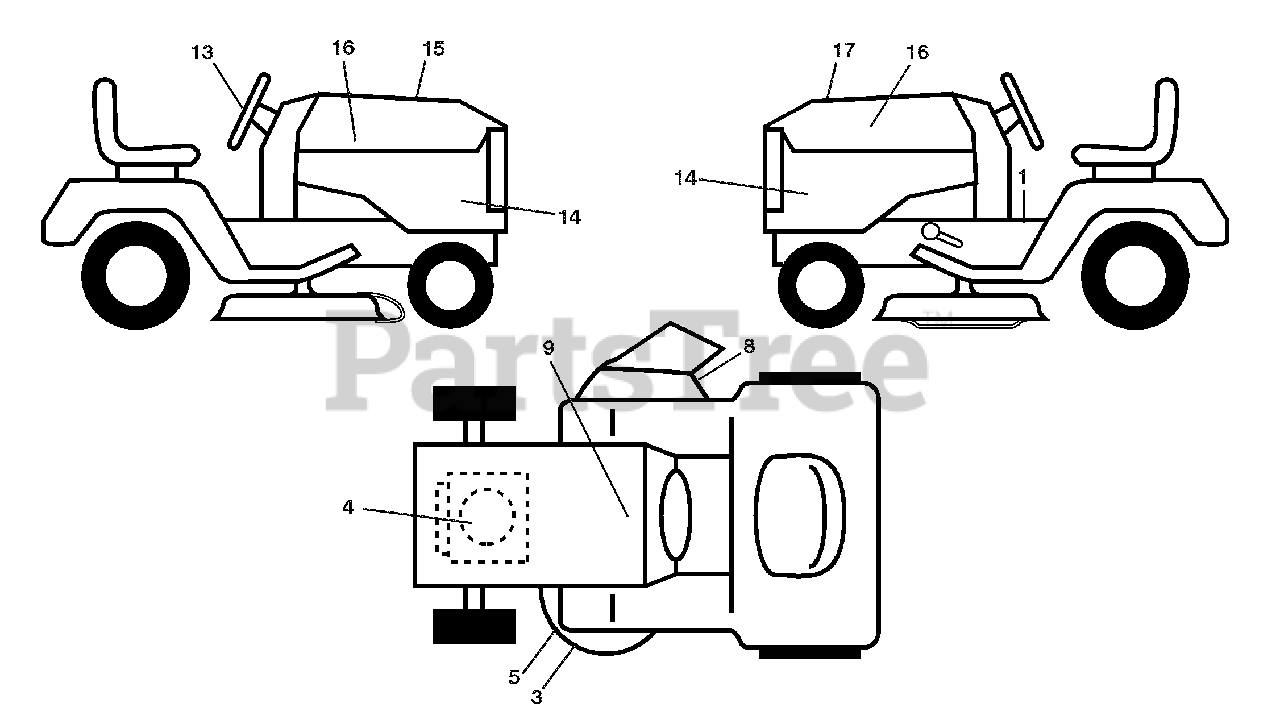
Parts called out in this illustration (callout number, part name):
1	Decal, Warning
3	Decal, Warning
4	Decal, Engine HP
5	Decal, Mower Caution
8	Decal, Mower Sch.
9	Decal, Battery Dnge/Poi
13	Decal, Steering Whl
14	Decal, Panel Side
15	Decal, Cust. Resp.
16	Decal, Hood Logo
17	Decal, Replacement
17	Decal, Bypass
17	Pad, Footrest, LH
17	Pad, Footrest, RH
17	Manual Owners
